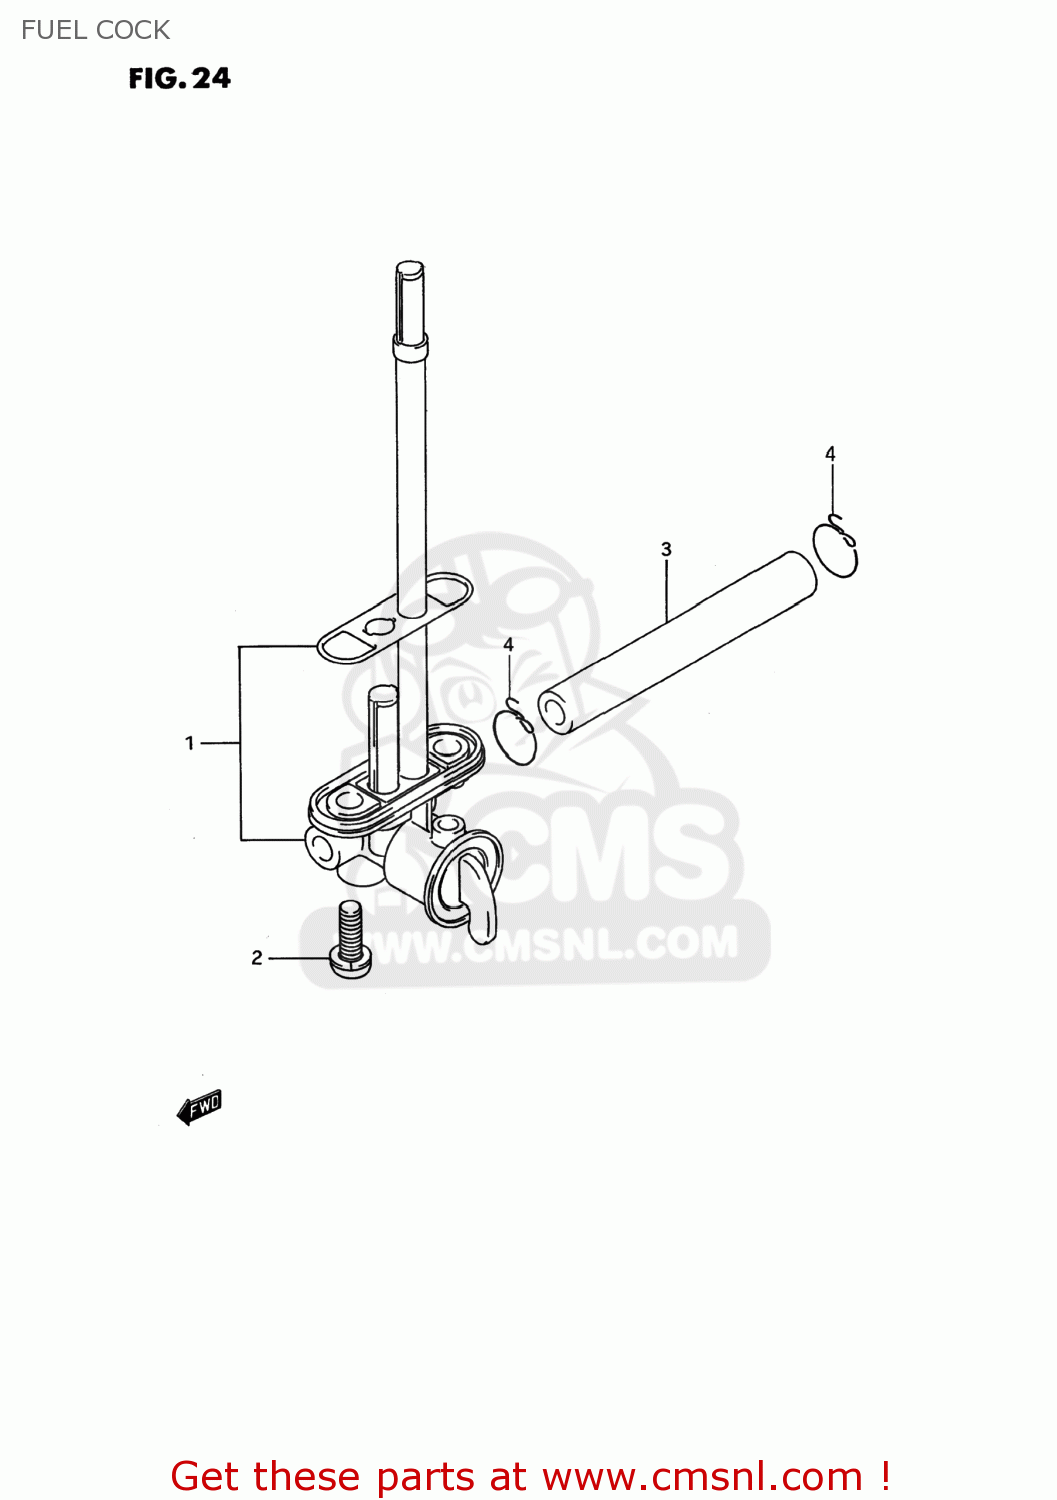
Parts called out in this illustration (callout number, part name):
1	COCK ASSY,FUEL
2	SCREW
3	HOSE
4	CLIP
